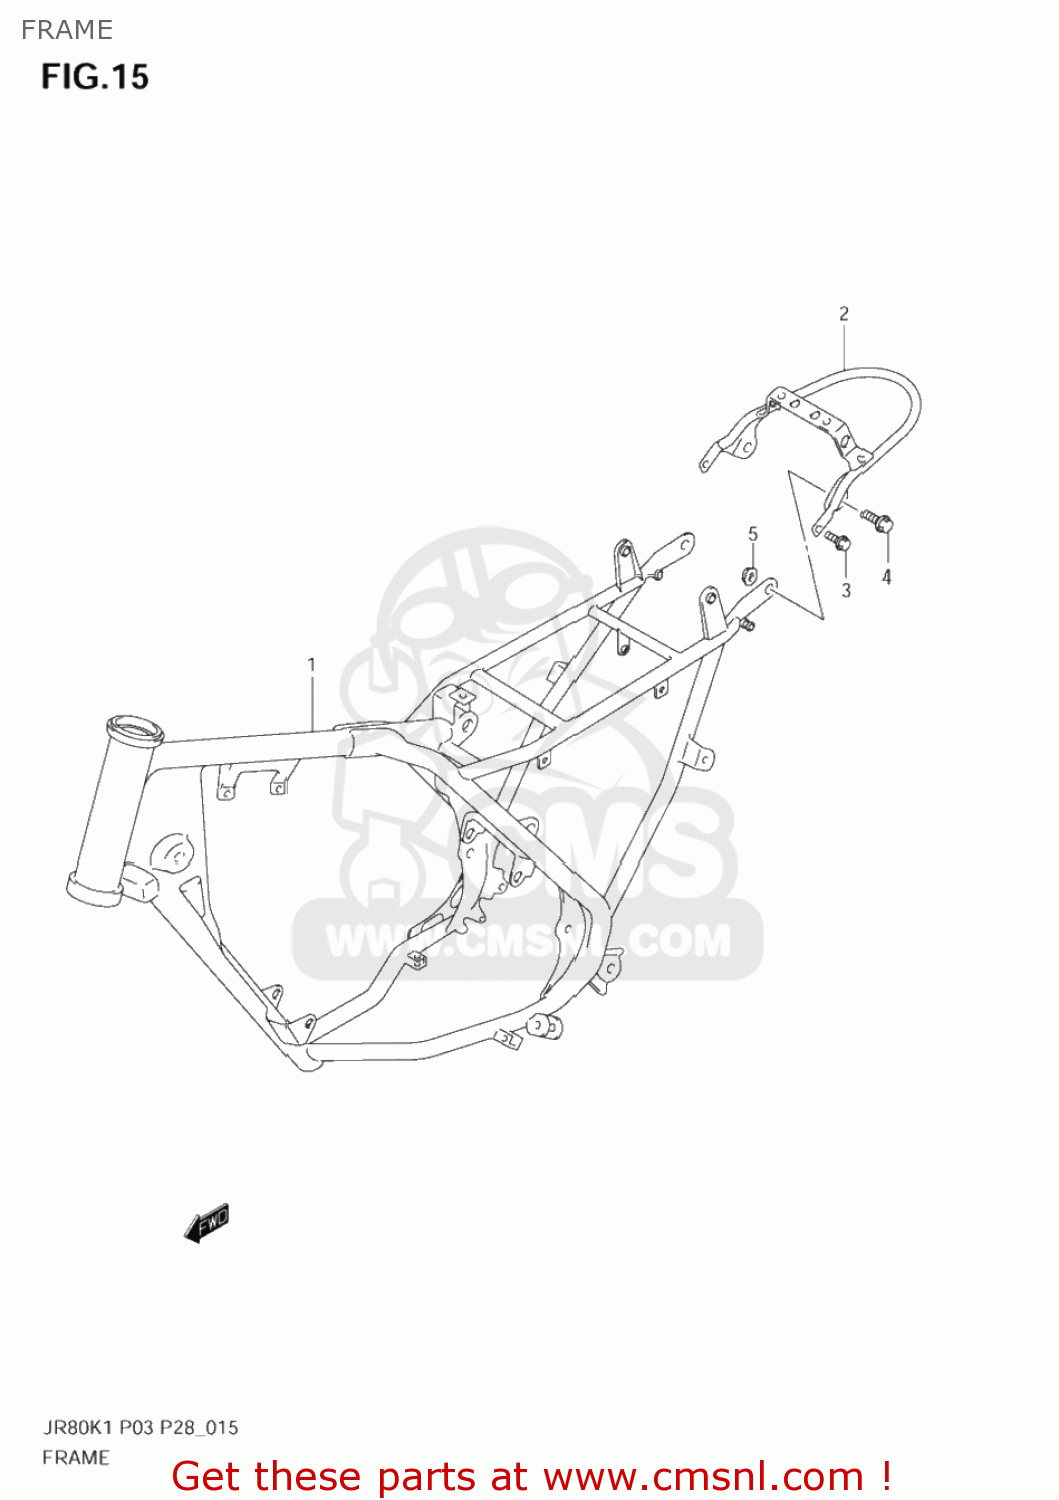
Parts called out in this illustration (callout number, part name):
1	FRAME(BLACK)
2	GRIP,RR
3	BOLT
4	BOLT
5	NUT
